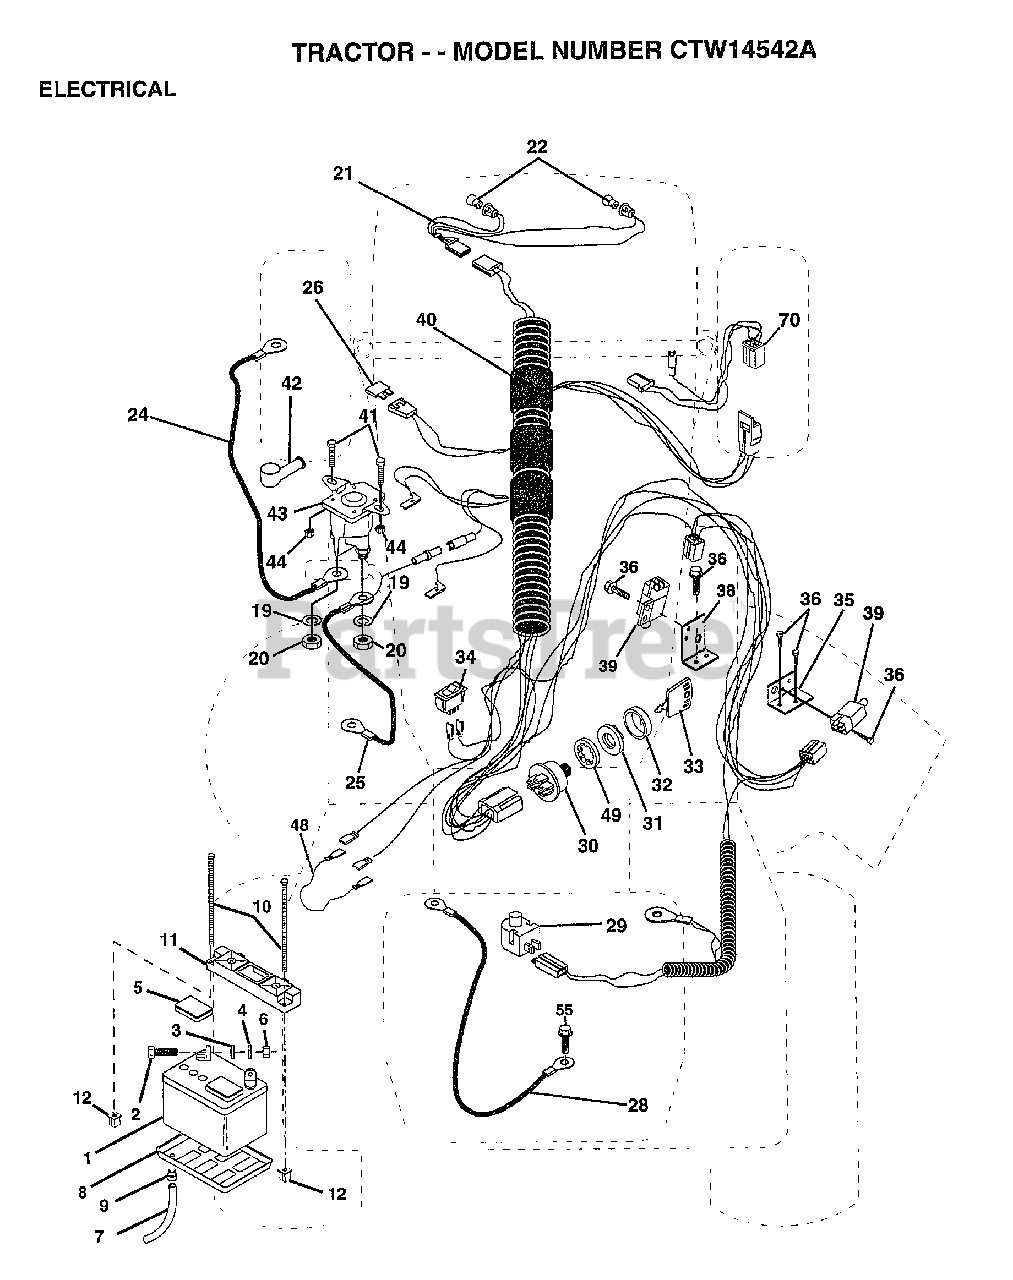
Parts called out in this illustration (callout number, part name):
2	BOLT LT
3	WASHER
4	LOCKWASHER
5	"CAP,BATTERY "
7	"DRAIN TU T, BATT"
8	"TRAY T, BATTERY"
9	HOSE CLAMP T
20	NUT
21	"HARNESS,LIGHT SOC"
22	HEADLAMP BULB
24	"CABLE T, BATTERY"
25	CABLE.6GA.22W/16W
26	FUSE HYT
28	CABLE.GRND.6GA.21
29	SWITCH SEAT
32	COVER KEY SWITCH
33	KEY MLD GEN DELTA
34	SWITCH LT
35	BRACKET LT
36	SCREW
38	BRACKET SWITCH IN
39	SWITCH INTERLOCKT
40	HARNESS.IGN.DASH.
41	BOLT HXHD FIN
44	NUT HXKEP 1/4X20
48	ADAPTER AMMETER
49	LOCKWASHER
55	SCREW LT
70	HARNESS.ENG.DUAL
